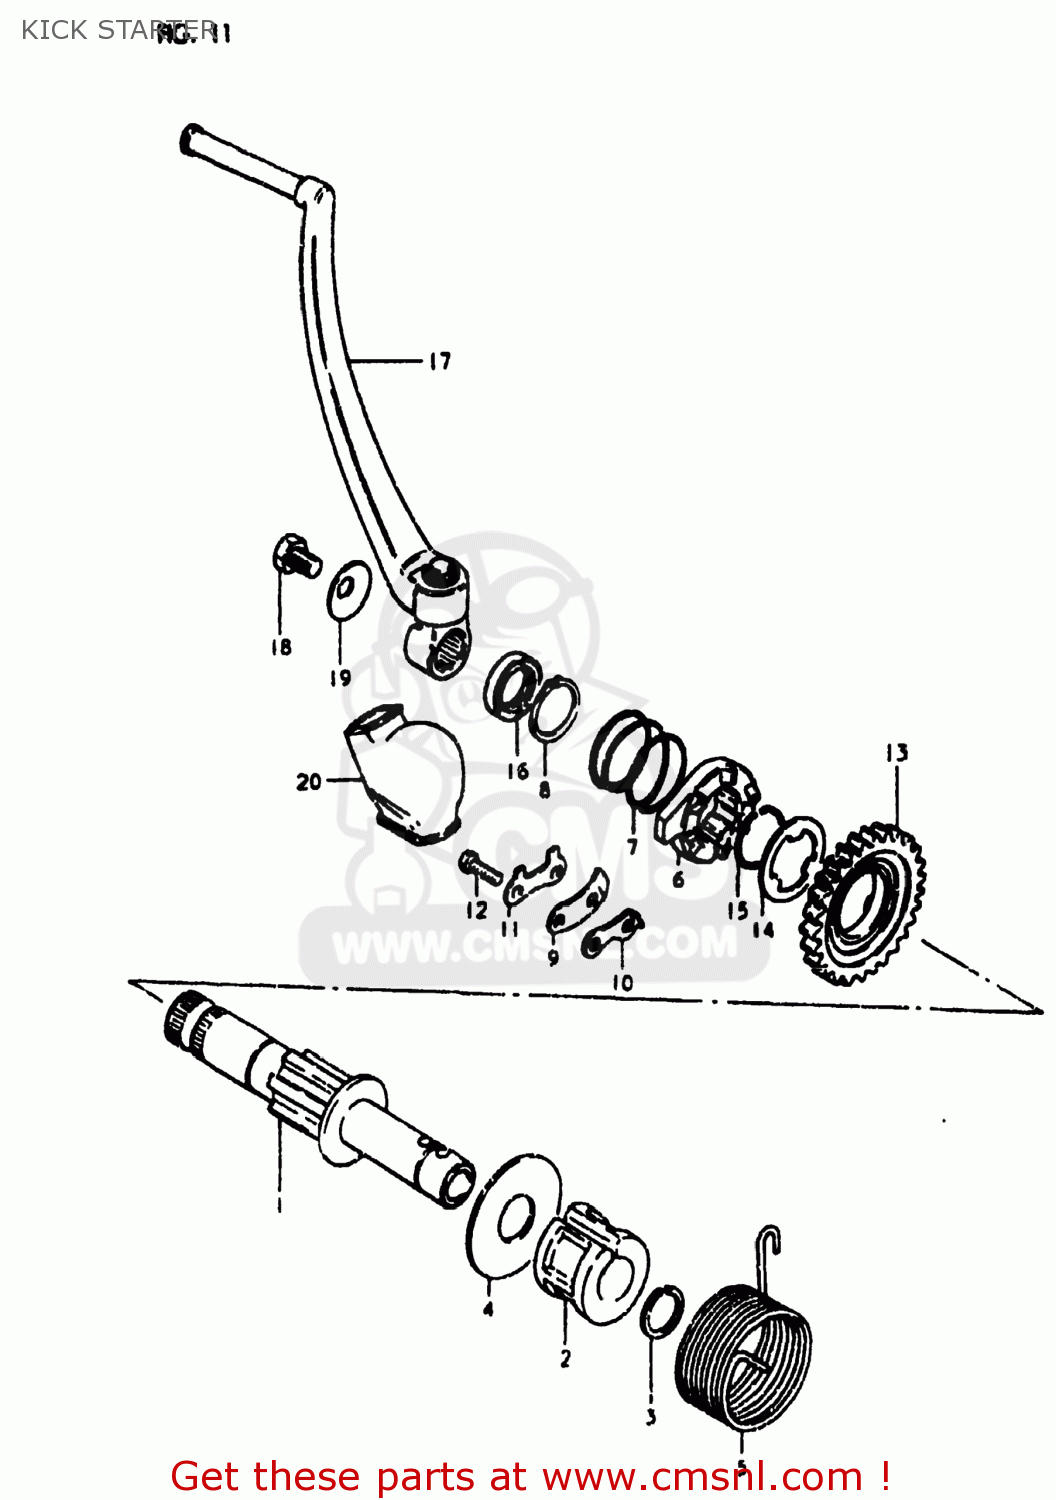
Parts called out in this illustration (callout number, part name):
1	SHAFT,KICK STARTER
2	GUIDE,KICK SHAFT SPRING
3	CIRCLIP
4	WASHER
5	SPRING
6	STARTER,KICK
7	SPRING
8	CIRCLIP
9	GUIDE,KICK STARTER
10	STOPPER,KICK STARTER
11	WASHER
12	BOLT, UPPER
13	GEAR,KICK STARTER DRIVE
14	WASHER,LOCK
15	RING,SNAP
16	SEAL,OIL(20X27X5)
17	LEVER ASSEMBLY,KICK STARTER
18	BOLT
19	WASHER(8.2X23X3.2)
20	COVER,KICK LEVER JOINT
